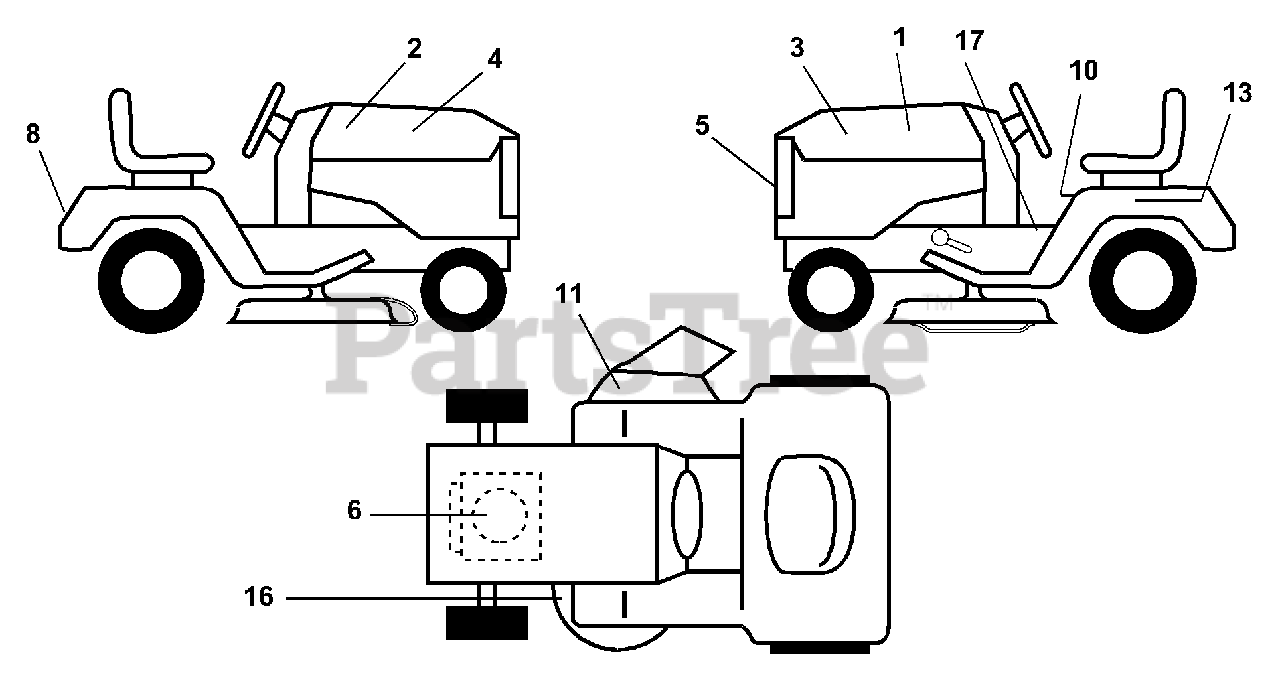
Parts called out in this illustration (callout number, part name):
1	Decal, Hood, L. H., Husqv.
2	Decal, Hood, R. H., Husqv.
3	Decal, Hood, L. H., LR120
4	Decal, Hood, R. H., LR120
5	Decal, Logo, Grill
6	Decal, Engine
8	Decal, Logo, Fender
10	Decal Caution Fender
11	Decal, Warning, Cut Finger, (Multi-Lang)
13	Decal, Caution, Battery
16	Decal, V-Belt Sch.
17	Decal, Inst. Oper.
